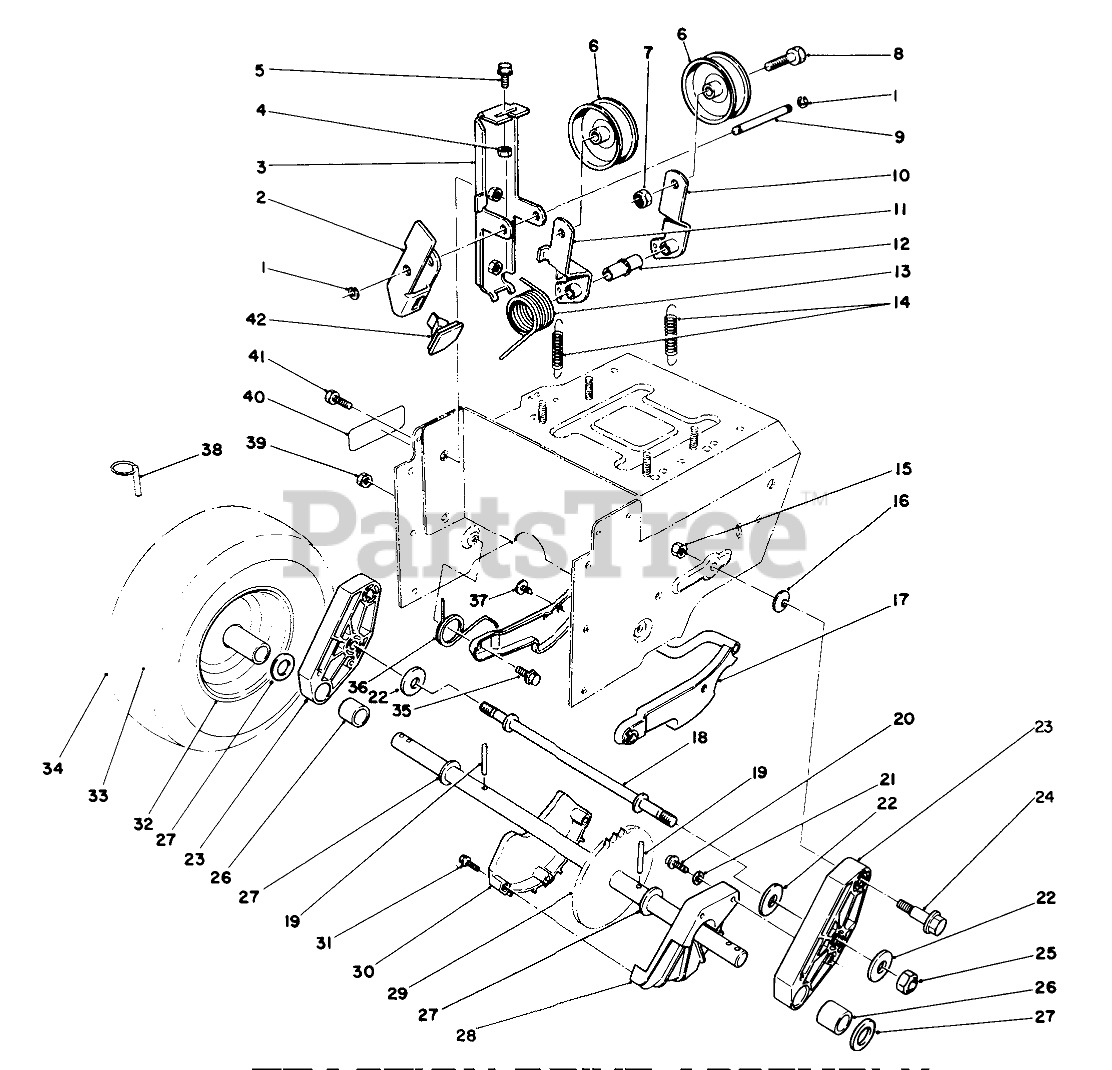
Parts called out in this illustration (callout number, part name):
1	RING-RETAINING
2	ARM-BRAKE
3	IDLER ARM BRACKET ASM
4	NUT-LOCK, NI
5	SCREW-HHF
6	PULLEY-IDLER
7	NUT-LOCK, NI
8	SCREW-HH
9	PIN-IDLER
10	ARM-IDLER, TRACTION
11	ARM-IDLER, IMPELLER
12	BUSHING-IDLER
13	SPRING-TORSION
14	SPRING-EXTENSION
15	NUT-LOCK, NI
16	WASHER-SPRING
17	Latch-Arm
18	ROD-LATCH
19	PIN-ROLL, SLOTTED
20	SCREW-HWH
21	WASHER-FLAT
22	WASHER-SUPPORT
23	Pivot Arm Assembly (Incl. Ref. #26)
24	BOLT-SHOULDER
25	NUT-LOCK, NI
26	BUSHING-AXLE
27	WASHER-THRUST
28	GUARD-CHAIN, LH
29	AXLE ASM
30	GUARD-CHAIN, RH
31	SCREW-PPH
32	WHEEL
33	TUBE-INNER
35	SCREW-SHOULDER
36	SPRING-LATCH, TORSION
37	FASTENER-PANEL
38	PIN-LYNCH
39	NUT-LOCK, NI
40	Decal-Warning
41	SCREW-HHF
42	PAD-BRAKE
